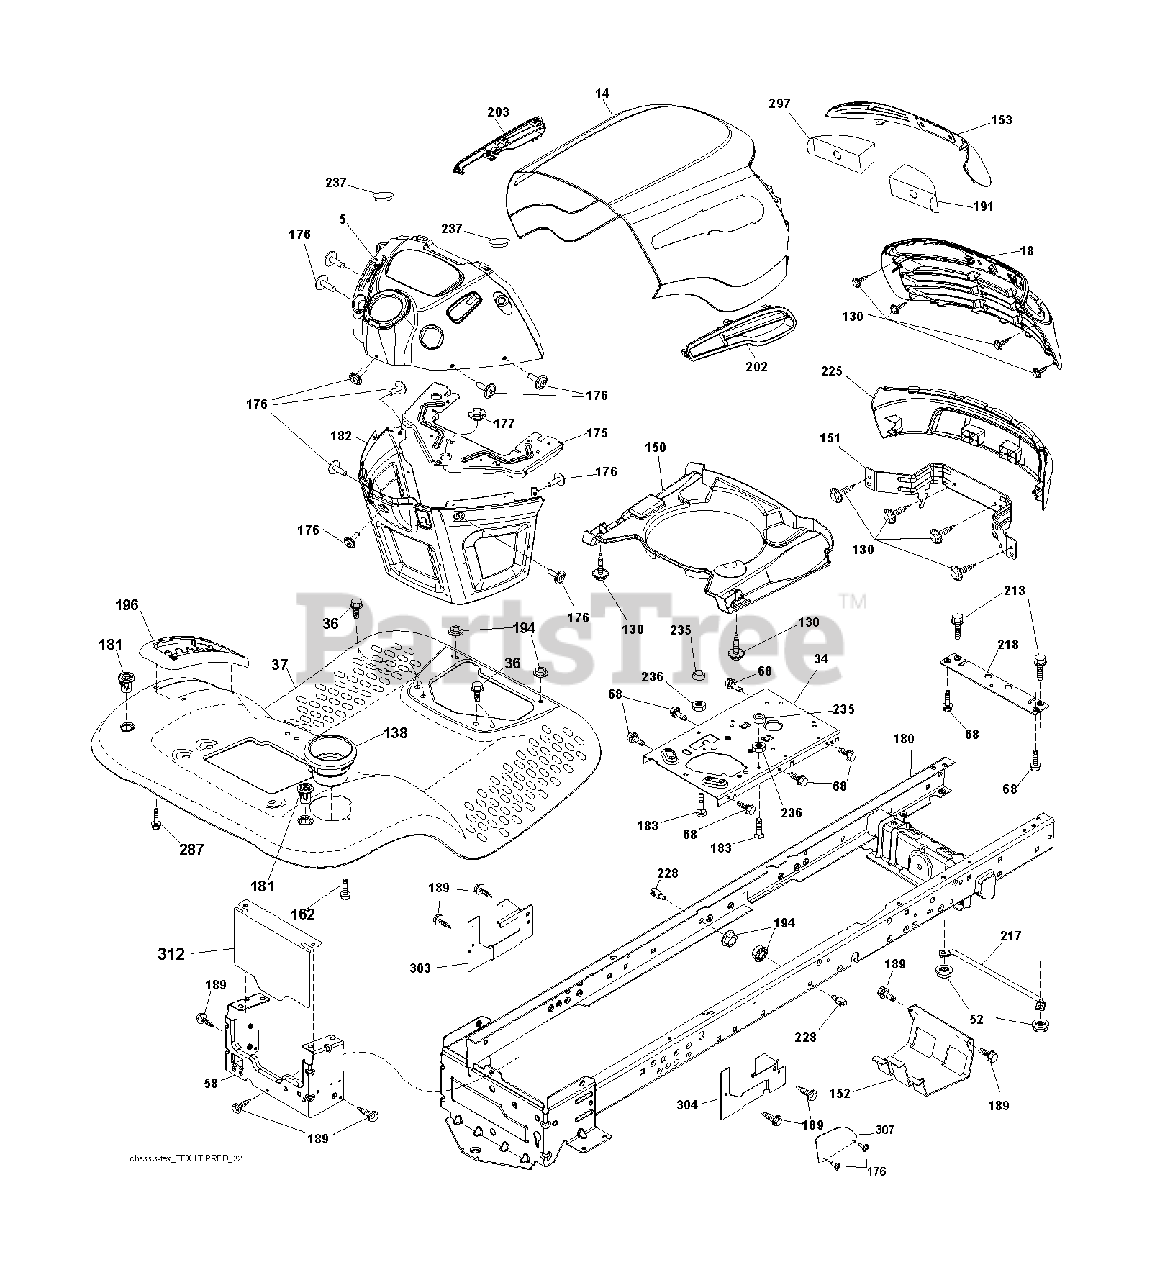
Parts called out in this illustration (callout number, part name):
5	DASH.PRED.LT.CC.ICY.SRVMDR.BLK
34	PLATE.ENGINE.WELDED.CHASSIS
36	SCREW 5/16"
52	LOCKNUT
58	DRAWBAR UPPER 2PC SMALL FENDER
130	SCREW.#10 X 0.750.BOS THREAD
138	CUPHOLDER.TL.TEX.BLACK
151	BRACKET.PIVOT.ALPHA.LT
152	SHIELD BROWNING
162	SCREW.HI-LO.CONSOLE
175	CROSSMEMBER
176	SCREW.#10-24X5/8.RN.QU
177	BUSHING STEERING
181	FEND/FTRST.PCH.CPH.NFW
182	DASH.LWER.PREDATOR/HUSQ.LT
183	BOLT.5/16-18X1-1/4 FULL.THREAD
189	SCREW
191	INSERT.REFLECT.PREDATOR.LT.RH
194	NUT LOCK HEX FLANGE 5/16-18
196	CONSOLE.ASM.DECKLFT.BL/RBT.TLT
213	BOLT
217	ROD.PIVOT.HOOD
218	X-PIECE.HOOD.STOP.NON/
228	STUD.FASTNER.W/ANTI-ROTATE
235	SPACER FENDER
236	NUT.CENTERLOCK.5/16-
237	PLUG.MOUNT.CARGO.BLK
297	REFLECTOR.INSERT.PRED.LH.LT
